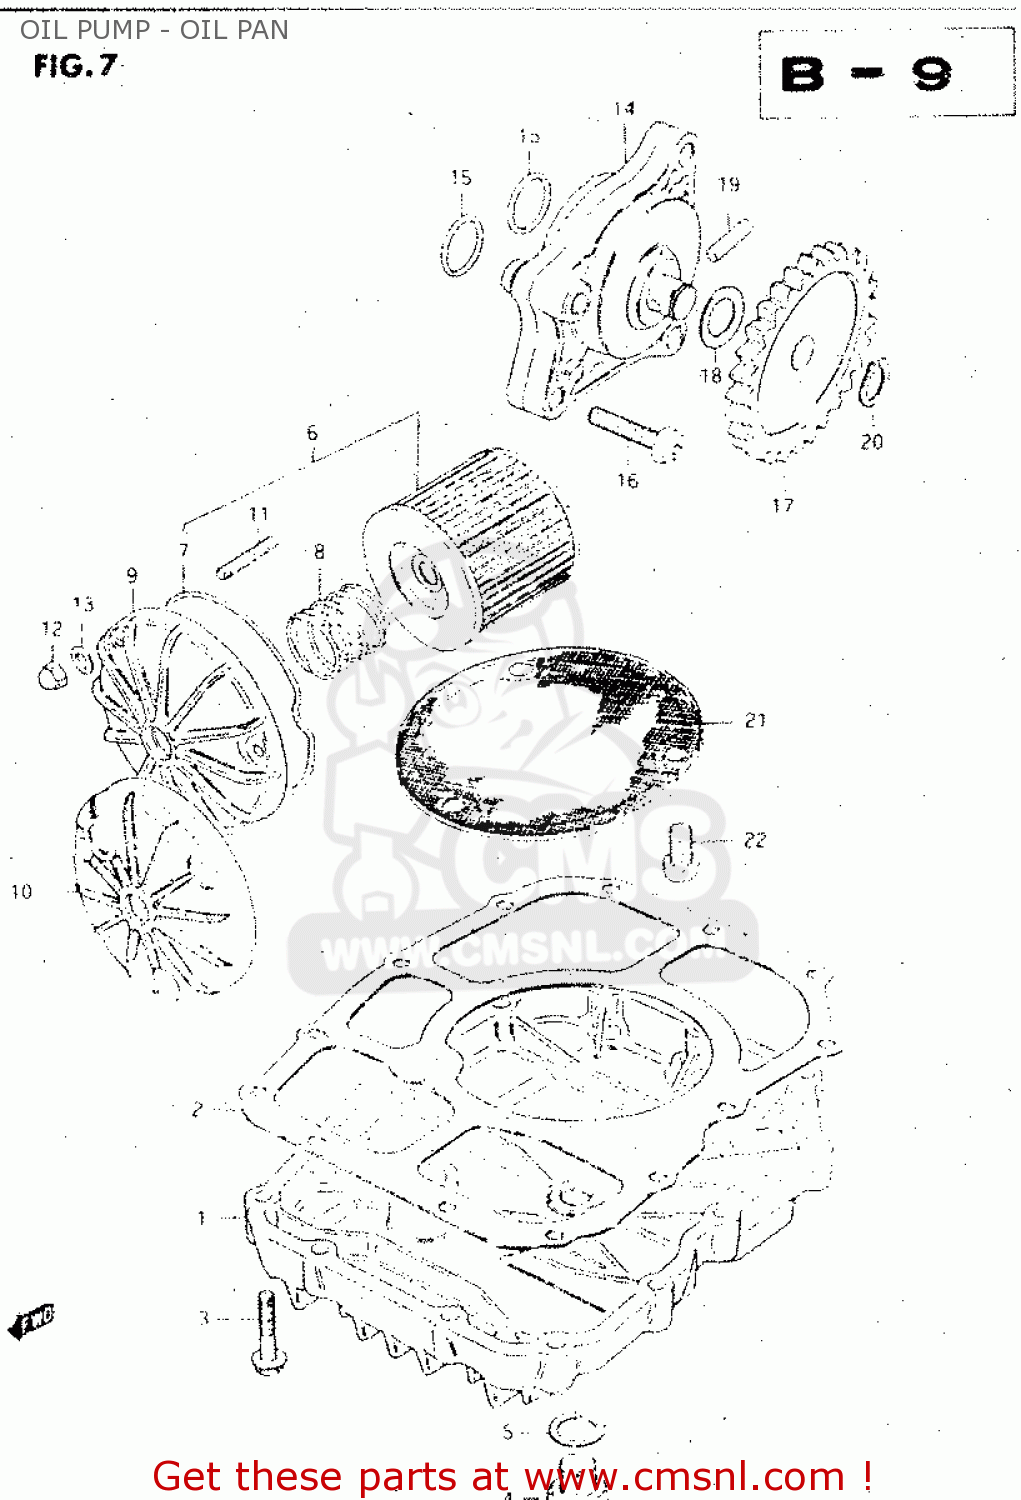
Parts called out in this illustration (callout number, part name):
1	PAN,OIL
2	GASKET,OIL PAN (MCA)
3	BOLT
4	PLUG
5	GASKET(14X19.2X2) (NAS)
6	ENGINE OIL FILTER SET
7	O RING,OIL FILTER CHAMBER CAP
8	SPRING
9	CAP,ENGINE OIL FILTER
10	CAP,OIL FILTER
11	STUD 6X20
12	NUT
13	WASHER
14	PUMP ASSEMBLY,ENGINE OIL
15	O RING(D:1.9,ID:13)
16	SCREW
17	GEAR,OIL PUMP DRIVEN
18	SHIM
19	PIN(4X15.8)
20	CIRCLIP
21	STRAINER,ENGINE OIL
22	SCREW 6X12
